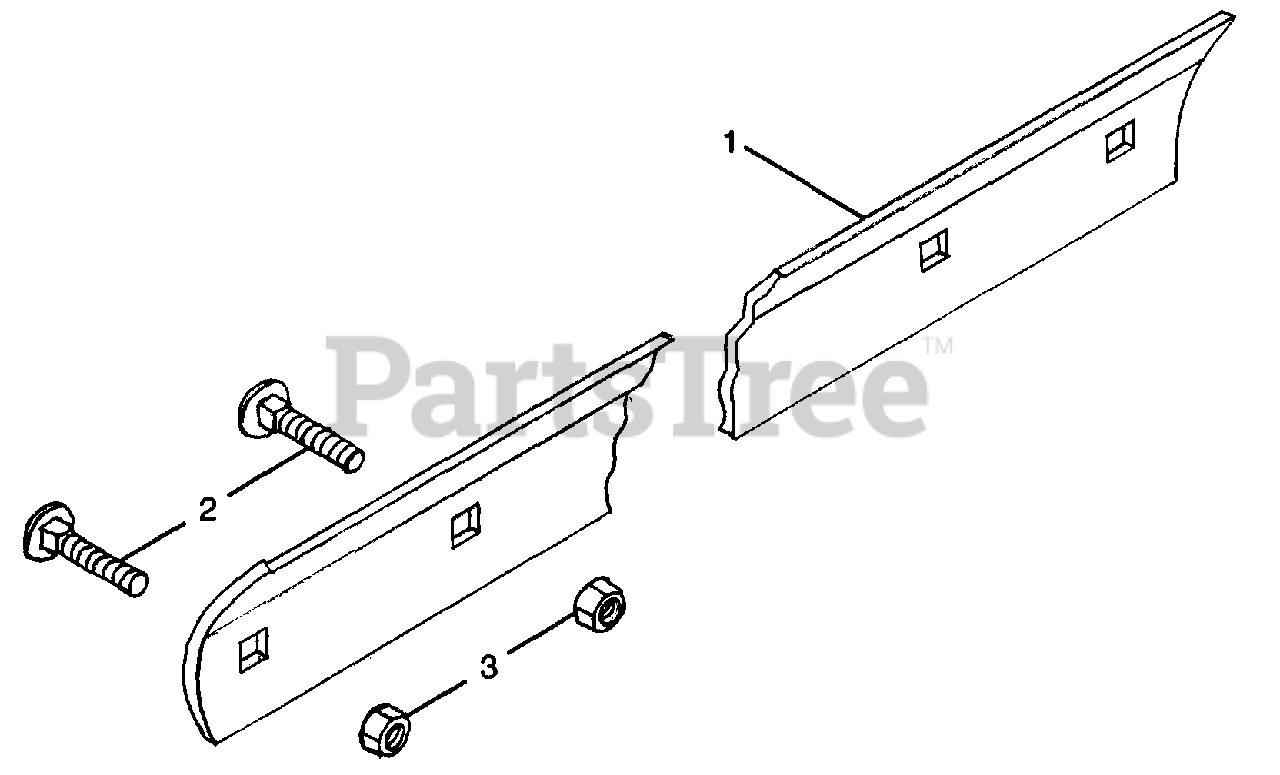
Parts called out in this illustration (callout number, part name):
1	CUTTER BAR
2	BLT-RDHDSQSHNK .31-18X.50 YZ
3	NUT-LK .312-18 GR A PL
